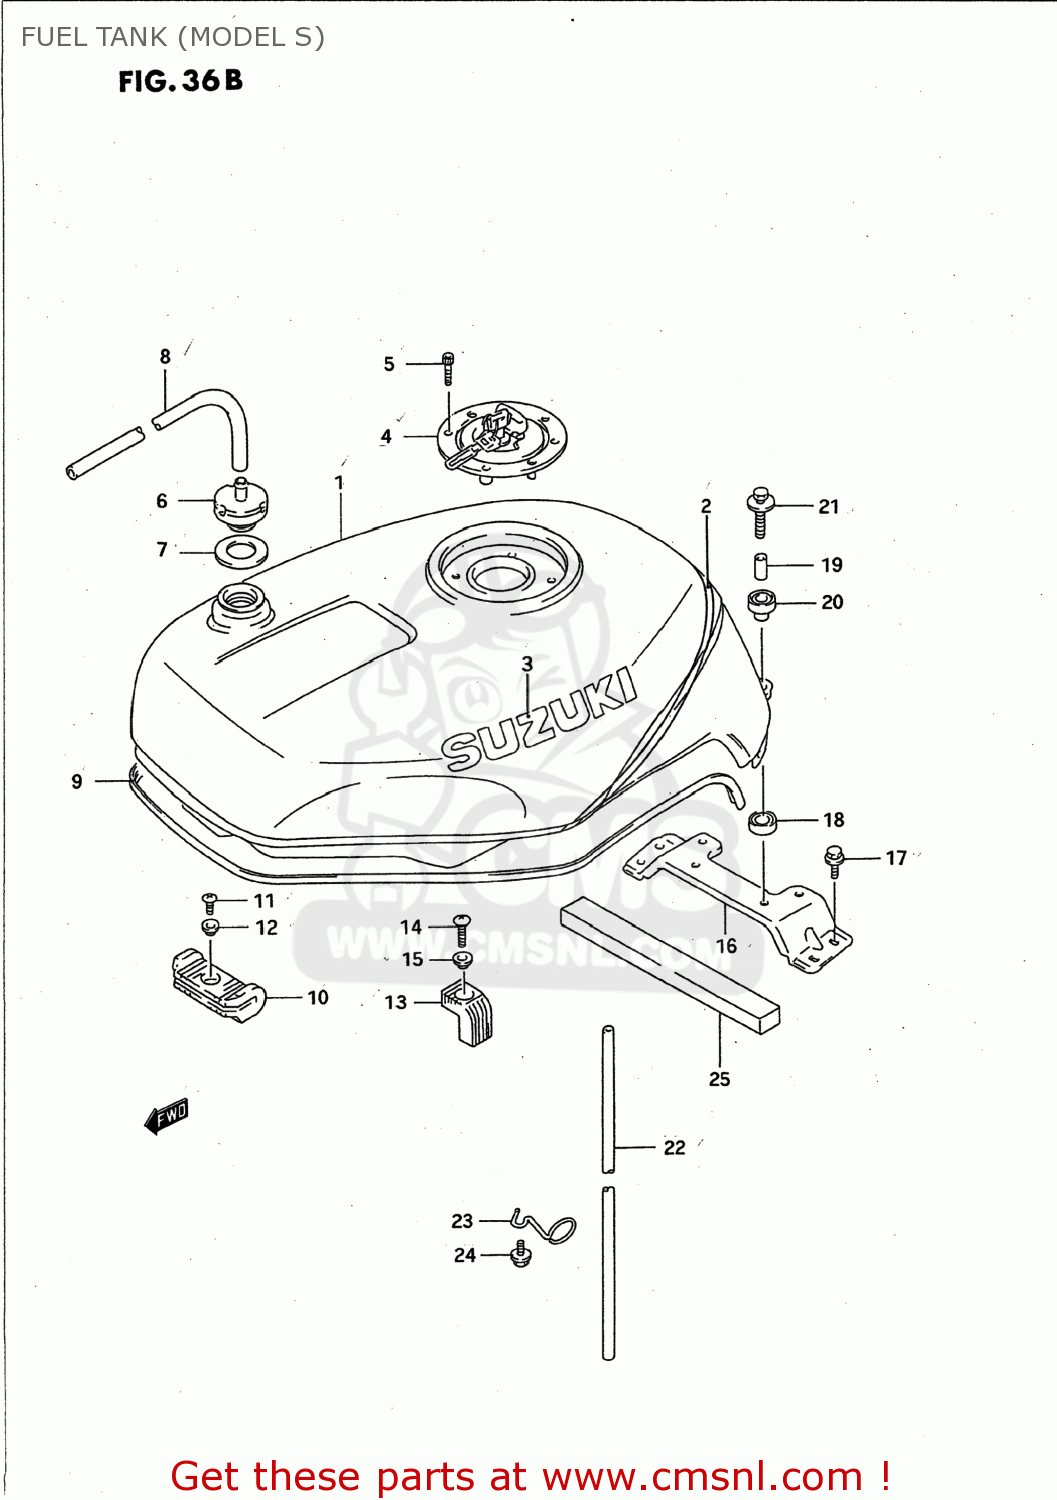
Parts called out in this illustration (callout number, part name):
1	TANK ASSEMBLY,FUEL
2	TAPE,FUEL TANK STRIPE
3	EMBLEM,FUEL TANK
4	CAP SET,FUEL TANK
5	BOLT(5X20)
6	PLUG,FUEL TANK BREATHER
7	GASKET 27X40X2.5 (NAS)
8	HOSE(5X8.2X600)
9	MOLDING,FUEL TANK
10	CUSHION,FUEL TANK FR
11	SCREW
12	WASHER
13	CUSHION,TANK SIDE
14	SCREW
15	WASHER
16	BRACKET,FUEL TANK,REAR
17	BOLT
18	CUSHION
19	SPACER
20	CUSHION
21	BOLT
22	HOSE(7X10.2X2000)
23	GUIDE,DRAIN HOSE
24	BOLT
25	CUSHION,AIR SEAL
